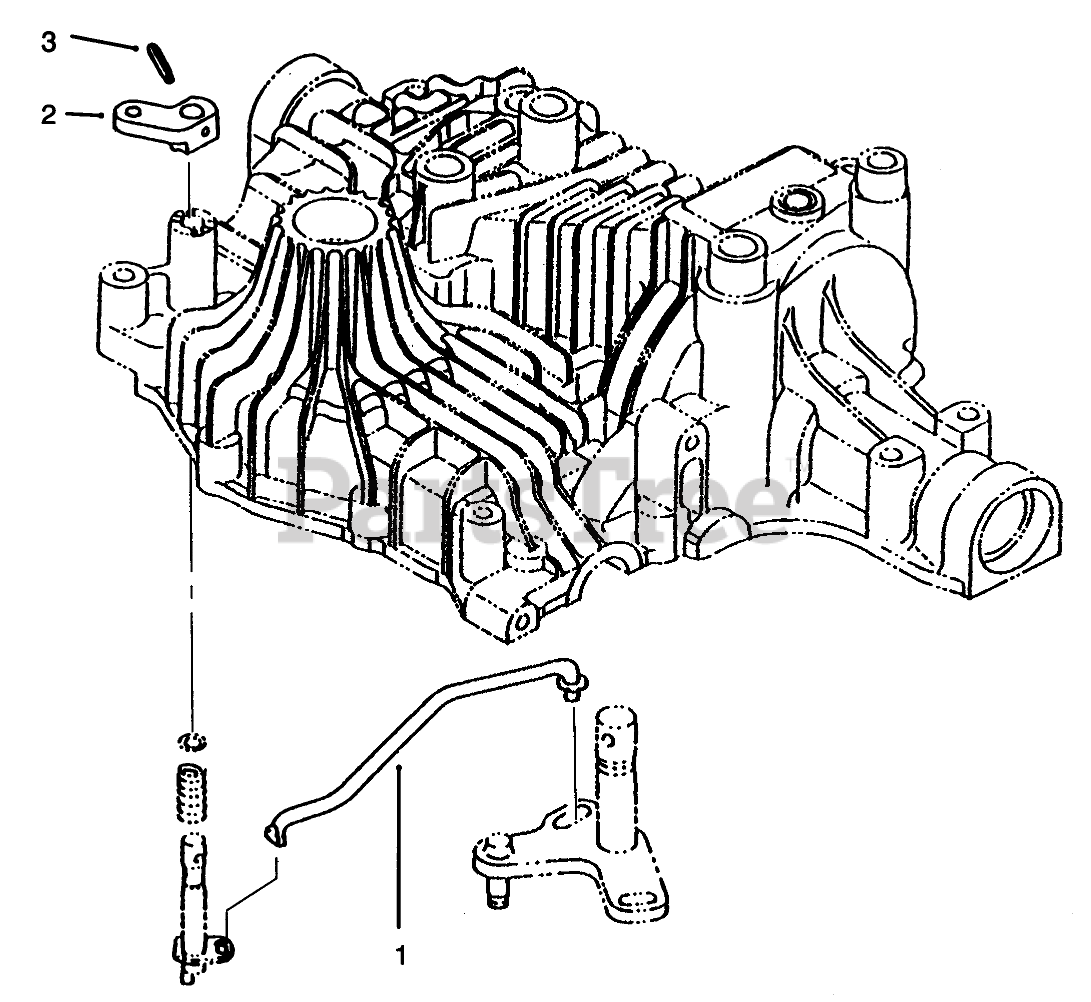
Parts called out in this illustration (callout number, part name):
1	Rod-Bypass (Only On: 72043, 72063, 72103)
2	Arm-Valve Release (Only On: 72043, 72063, 72103)
3	Pin-Roll (Only On: 72043, 72063, 72103)
